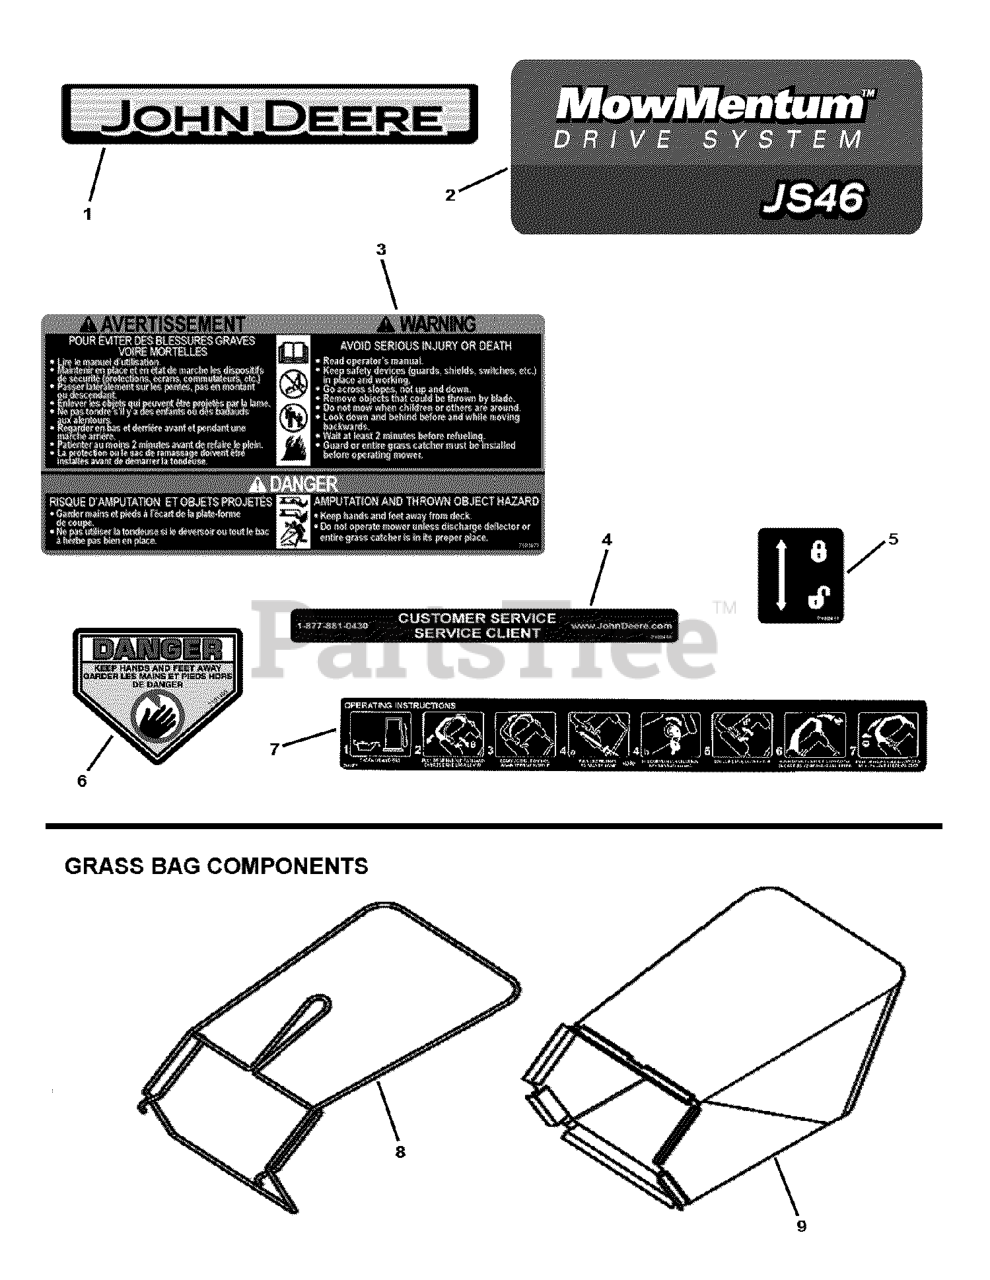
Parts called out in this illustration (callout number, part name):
1	DECAL, FRONT, JOHN DEERE JS36/JS46
2	DECAL, JS46 MOWMENTUM
3	DECAL, WB SAFETY, FRENCH/ENGLISH
4	DECAL, CUSTOMER SERVICE, FRENCH
5	DECAL, NEUTRAL LOCK, FC
6	DECAL, CPSC, FRENCH/ENGLISH
7	DECAL, OPERATION, JD
8	BAG FRAME, RD
9	BAG, GRASS, 22" REAR DISCHARGE
